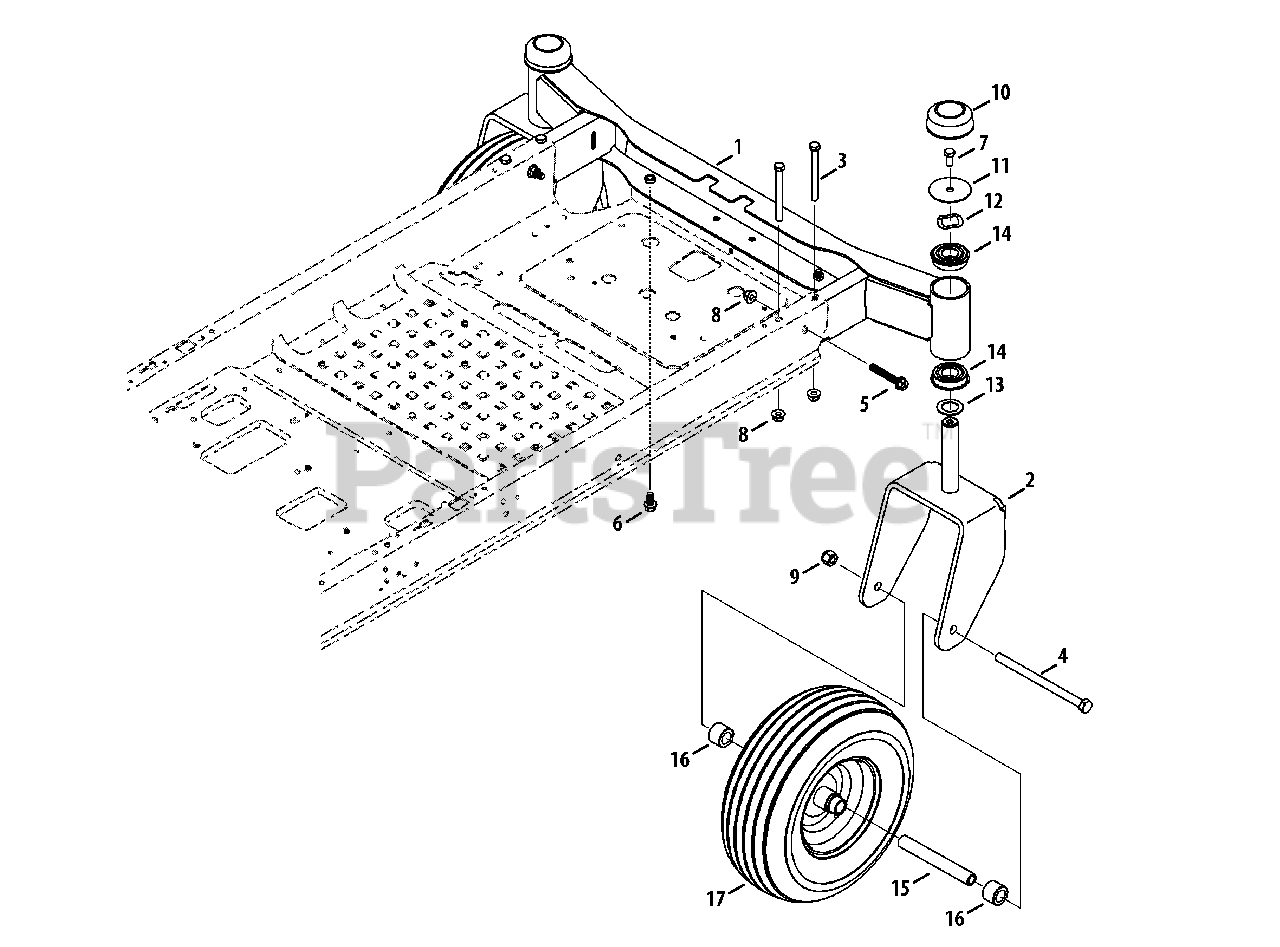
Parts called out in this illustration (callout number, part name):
2	Caster Wheel Bracket
3	Hex Cap Screw, 3/8-16 x 3.75
4	Hex cap Screw, 1/2-20 x 7.25
5	Hex Flange Screw, 3/8-16 x 2.25
6	Screw TT, 3/8-16 x .750
7	Hex Cap Screw, 3/8-16 x .750
8	Flange Lock Nut, 3/8-16
9	Hex Lock Nut, 1/2-20
11	Flat Washer, .406 x 2.50 x .060
12	Wave Washer, 1.25 x 1.00 x .300
13	Flat Washer, 1.010 x 1.56 x .060
14	Ball Bearing
15	Spacer, .51 x .75 x 5.825
16	Hub, .76 x 1.23 x .92
17	Wheel Assembly, 13 x 5-6
